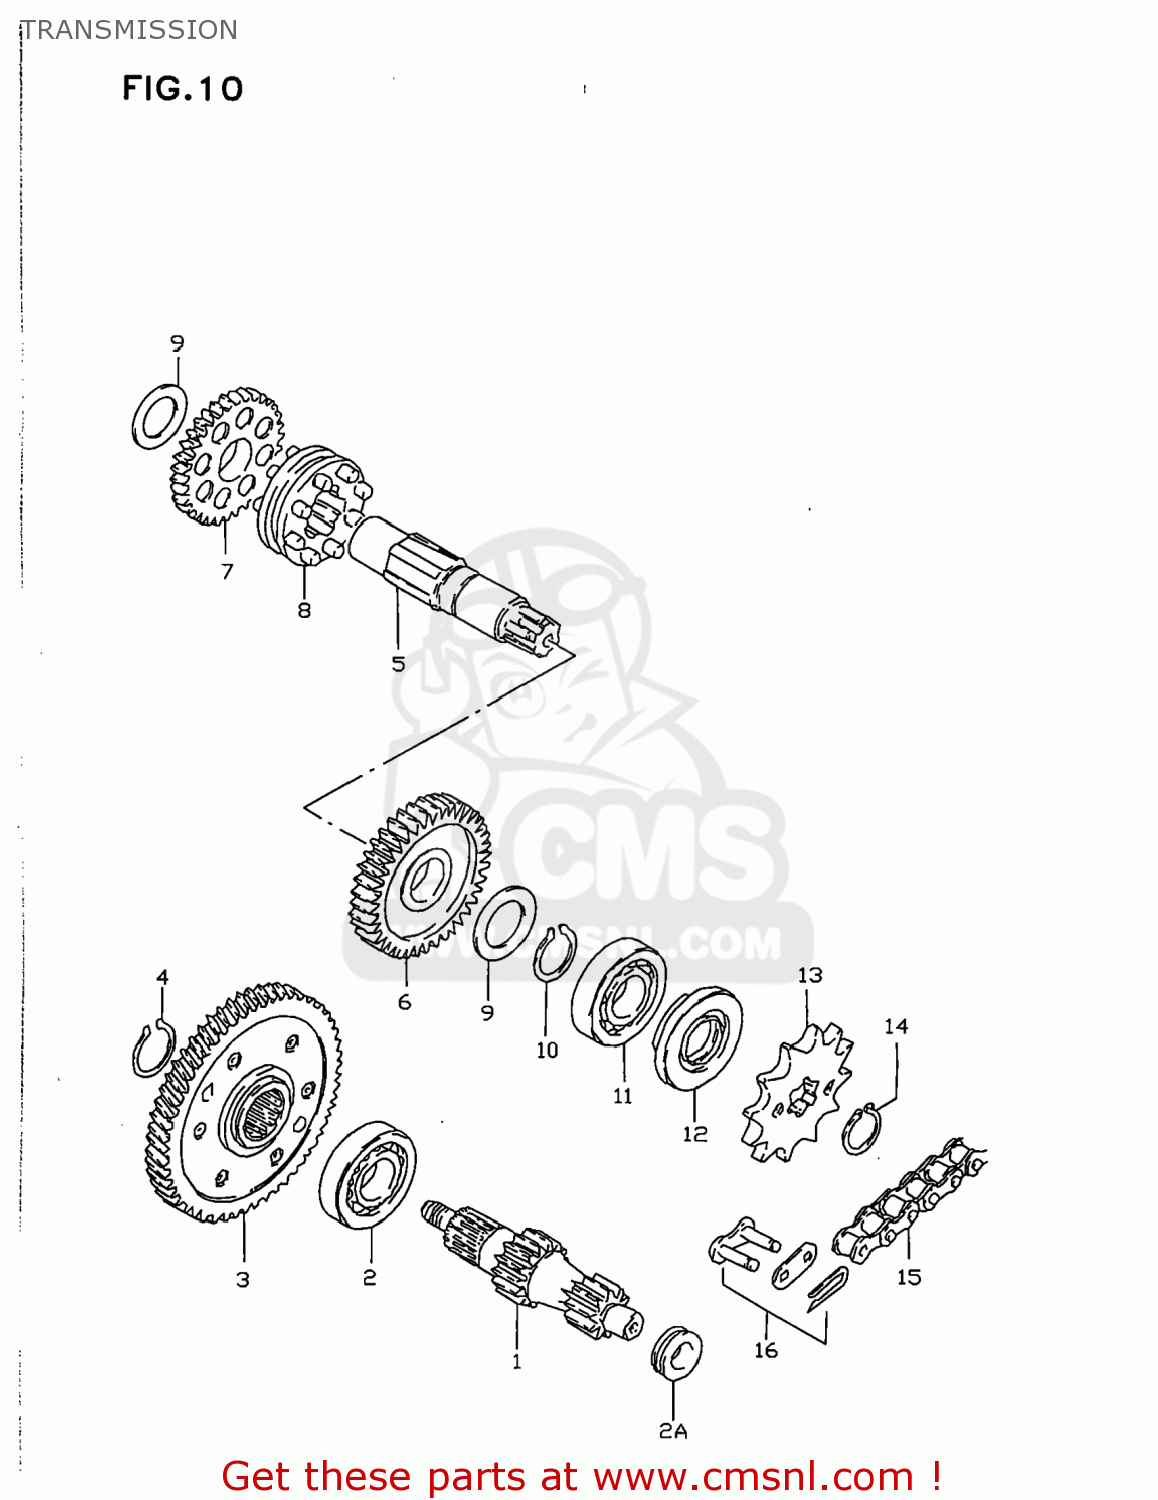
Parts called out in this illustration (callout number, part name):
1	SHAFT,COUNTER
2	BEARING(17X40X12)
2A	BUSH
3	GEAR ASSY,PRI DRIVEN
4	CIRCLIP
5	SHAFT,DRIVE
6	GEAR 1ST DRIVEN
7	GEAR 2ND DRIVEN
8	WHEEL,1ST GEAR
9	WASHER,THRUST
10	CIRCLIP
11	BEARING(17X40X12)
12	OIL SEAL (17X29X7)
13	SPROCKET,ENGINE
14	CIRCLIP 16MM
15	CHAIN,DRIVE
16	JOINT
